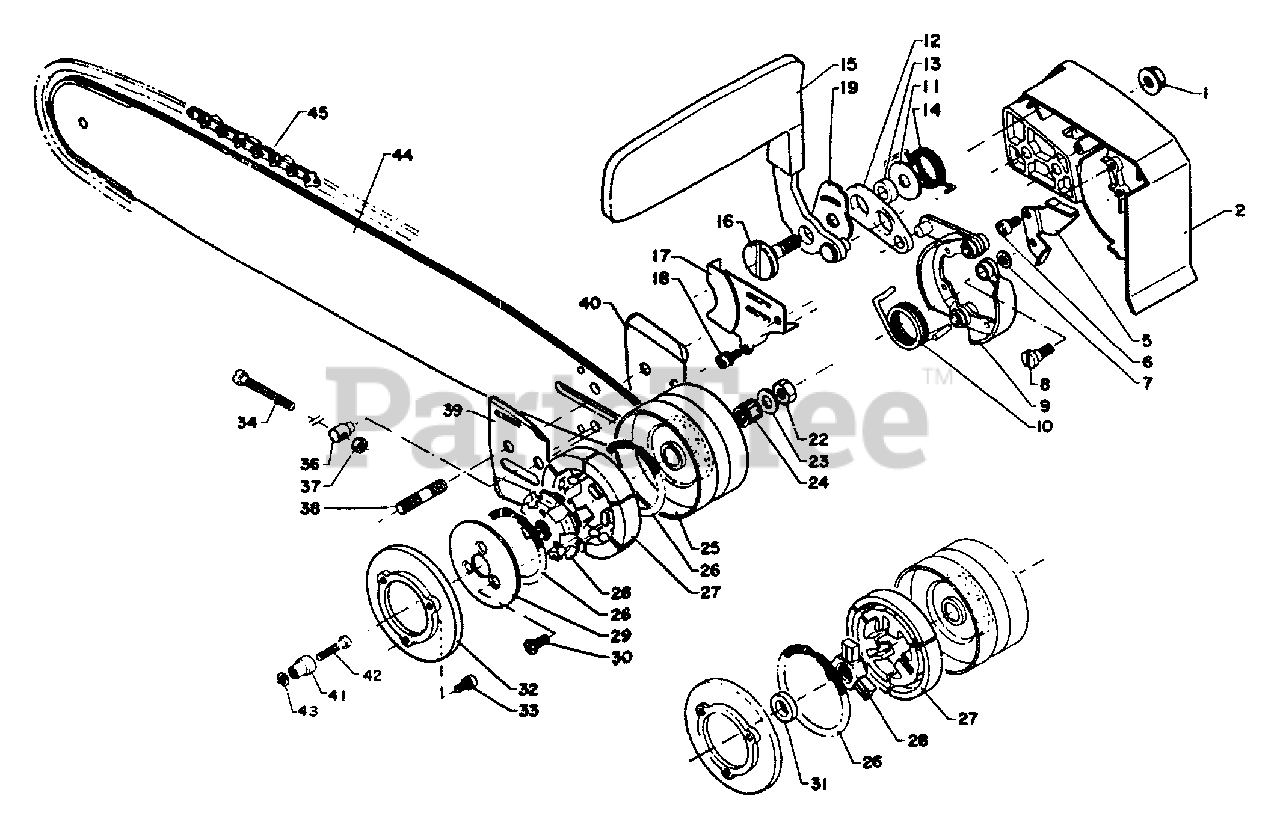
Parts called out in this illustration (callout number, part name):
1	NUT, FLANGE M8×1.25
2	GUIDE BAR COVER
5	GUIDE, BRAKE SHOE
6	SCREW 5×8
9	SHOE, BRAKE
10	SPRING, BRAKE
11	SPACER
12	CONNECTOR
13	SPACER, BRAKE HANDLE
14	SPRING, RETURN
15	HANDLE, BRAKE
17	SEAL, DUST
18	SCREW 4×10
19	WASHER
22	LOCKNUT
23	WASHER
24	BEARING, NEEDLE
25	DRUM, CLUTCH
26	SPRING, CLUTCH
27	SHOE, CLUTCH
28	HUB, CLUTCH
29	PLATE, CLUTCH
30	SCREW 5×16
31	WASHER, CLUTCH
32	SEAL, DUST
33	SCREW - 4×10
34	SCREW, ADJUSTER
36	TENSIONER, CHAIN
37	LOCKNUT - 5
38	STUD, GUIDE BAR
39	PLATE, GUIDE - INNER
40	PLATE, GUIDE - OUTER
41	CATCHER, CHAIN
42	SCREW - 5×25
43	WASHER, FLAT 5.5×10×0.8
44	GUIDE BAR
